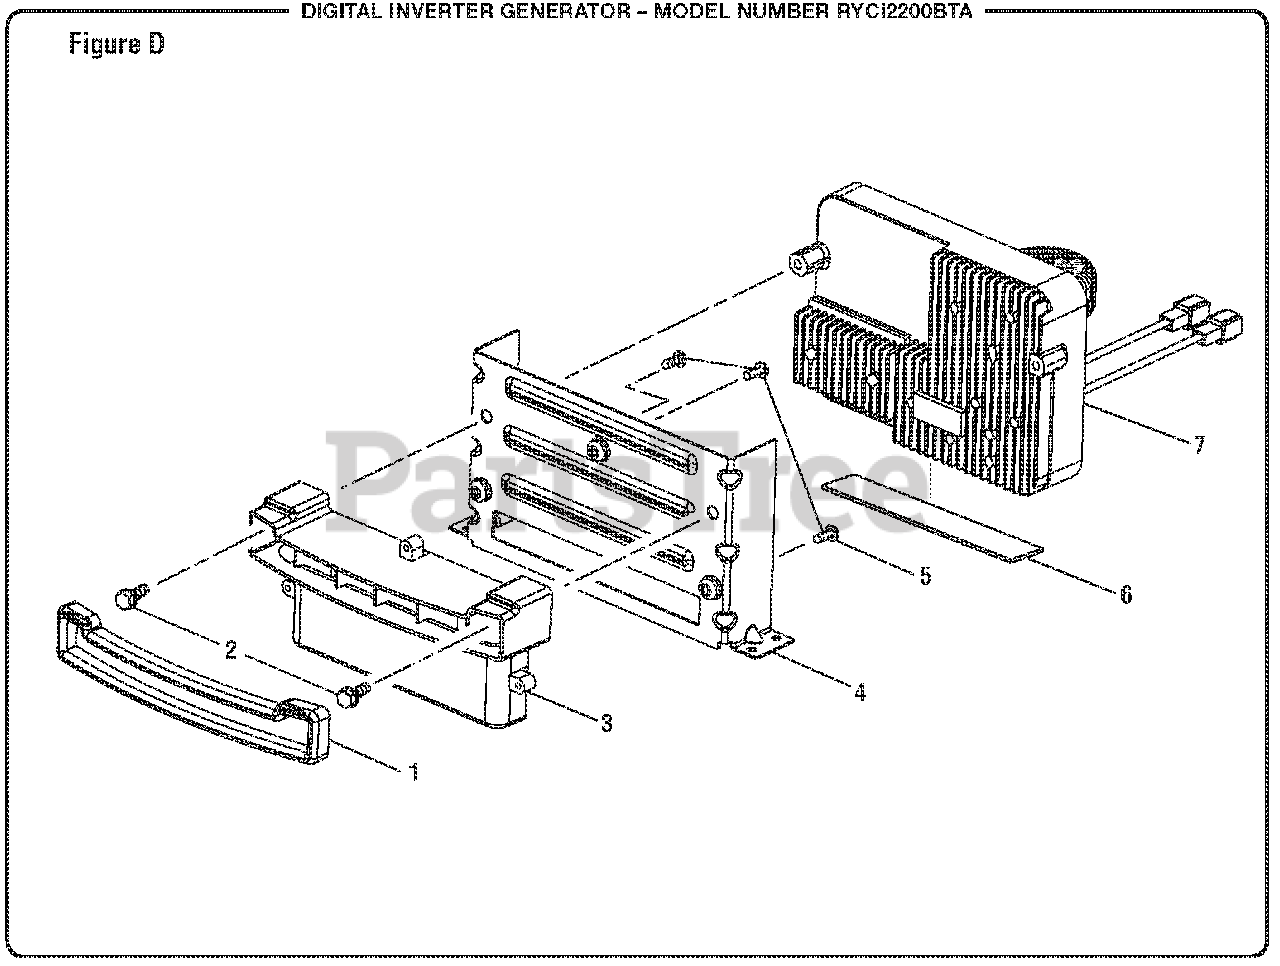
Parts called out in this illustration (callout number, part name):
1	Rubber Trim
2	Bolt (M6 x 12 mm, Hex Hd.)
3	Baffle (Engine Intake)
5	Screw w/Washer (M4 x 10 mm, T20 Torx Pan Hd.)
6	Rubber Pad
7	Inverter Module
